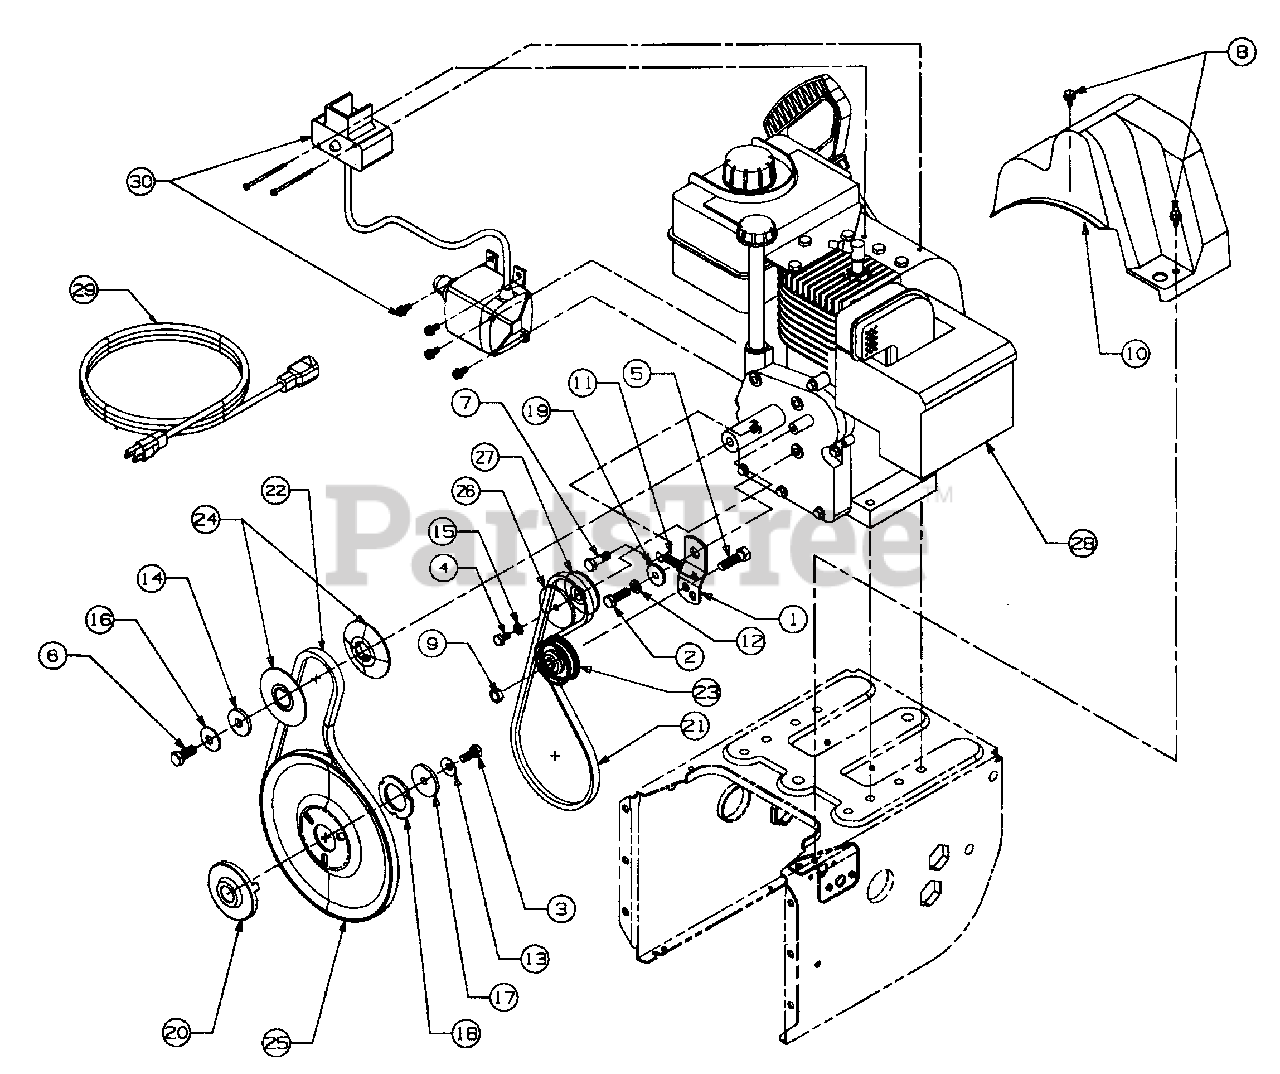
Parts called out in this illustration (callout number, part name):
3	Screw, Hex Cap, 5/16-24 x .75 GR5
4	Screw, Hex Cap, 1/4-28 x .5
5	Screw, Hex Cap, 3/8-16 x 1.25
6	Screw, Hex Cap, 3/8-24 x .875 GR8
7	Screw, Hex Cap, 5/16-24 x 1.0 GR5
8	Screw, Hex Wash Hd Tapp 1/4-14 x .625
9	Nut, Hex Jam Lock, 3/8-16
10	Belt Cover
11	Spring, Extension
12	Washer, Flat, .349 x .879 x .063
13	Washer, Bell, .345 x .88 x .06
14	Washer, .406 x 1.25 x .157 Hdn
15	Washer, Lock 1/4
16	Washer, Bell, .39 x 1.13 x .062
17	Washer, Flat, .34 x 1.5 x .15 Hdn
18	Washer, Special 1.28 x 2.0 x .119
20	Pulley, Adapter
21	V-Belt, 3/8 x 29
22	V-Belt, 3v x 34.9
23	Idler, Flat
24	Pulley, Half
25	Pulley, Auger
26	Pulley Half
27	Pulley, Half
28	Engine
29	Cord Extension
30	Starter Kit
